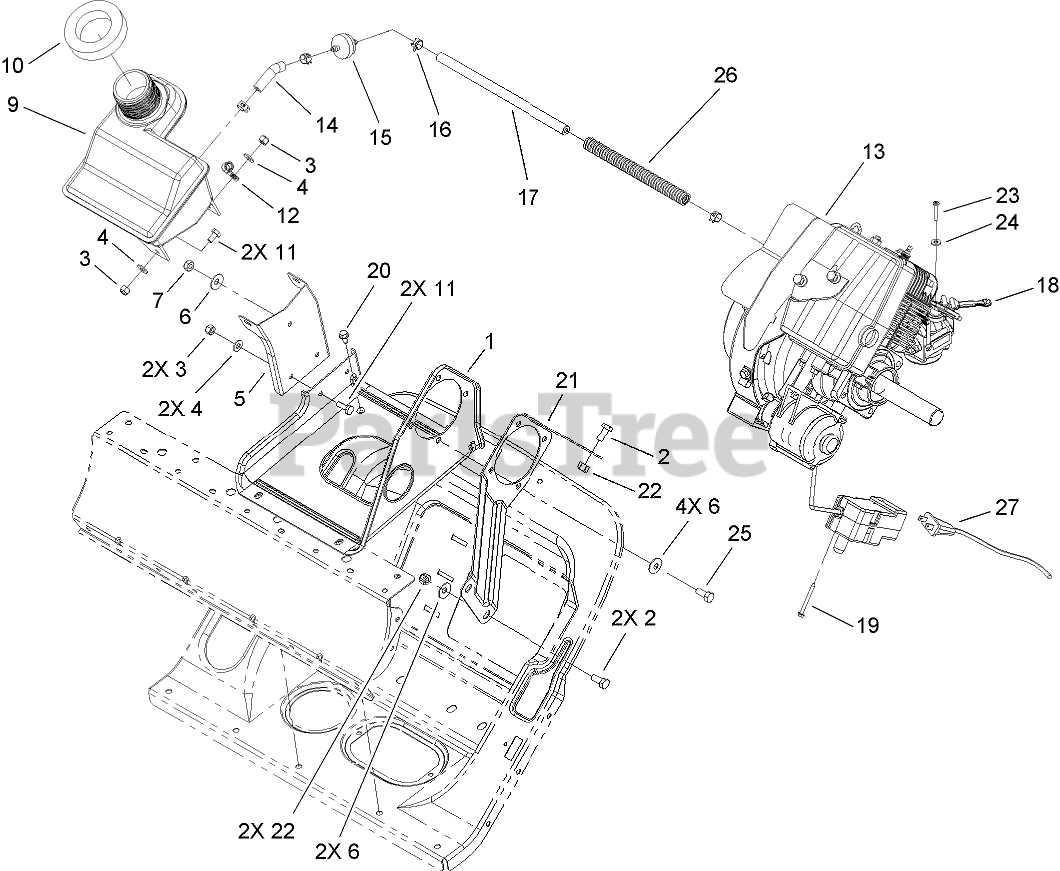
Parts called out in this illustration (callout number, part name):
1	SUPPORT-ENGINE
2	SCREW-HH
3	NUT-LOCK, NI
4	WASHER-FLAT
5	SUPPORT-RECOIL
6	WASHER-BELLEVILLE
7	NUT-LOCK, NI
9	Tank-Gas
10	SEAL-FOAM
11	SCREW-HH
12	CLAMP
14	HOSE-FUEL
15	FILTER-FUEL
16	CLAMP-HOSE
17	HOSE-FUEL
18	LEVER-CHOKE
19	SCREW-PLASTITE
20	SCREW-HWH, THREAD ROLL
21	BRACE-ENGINE
22	NUT-LOCK, NI
23	SCREW-PPH, PLASTITE
24	WASHER-FLAT
25	SCREW-HH
26	CONDUIT
27	CORD-ELECTRIC
